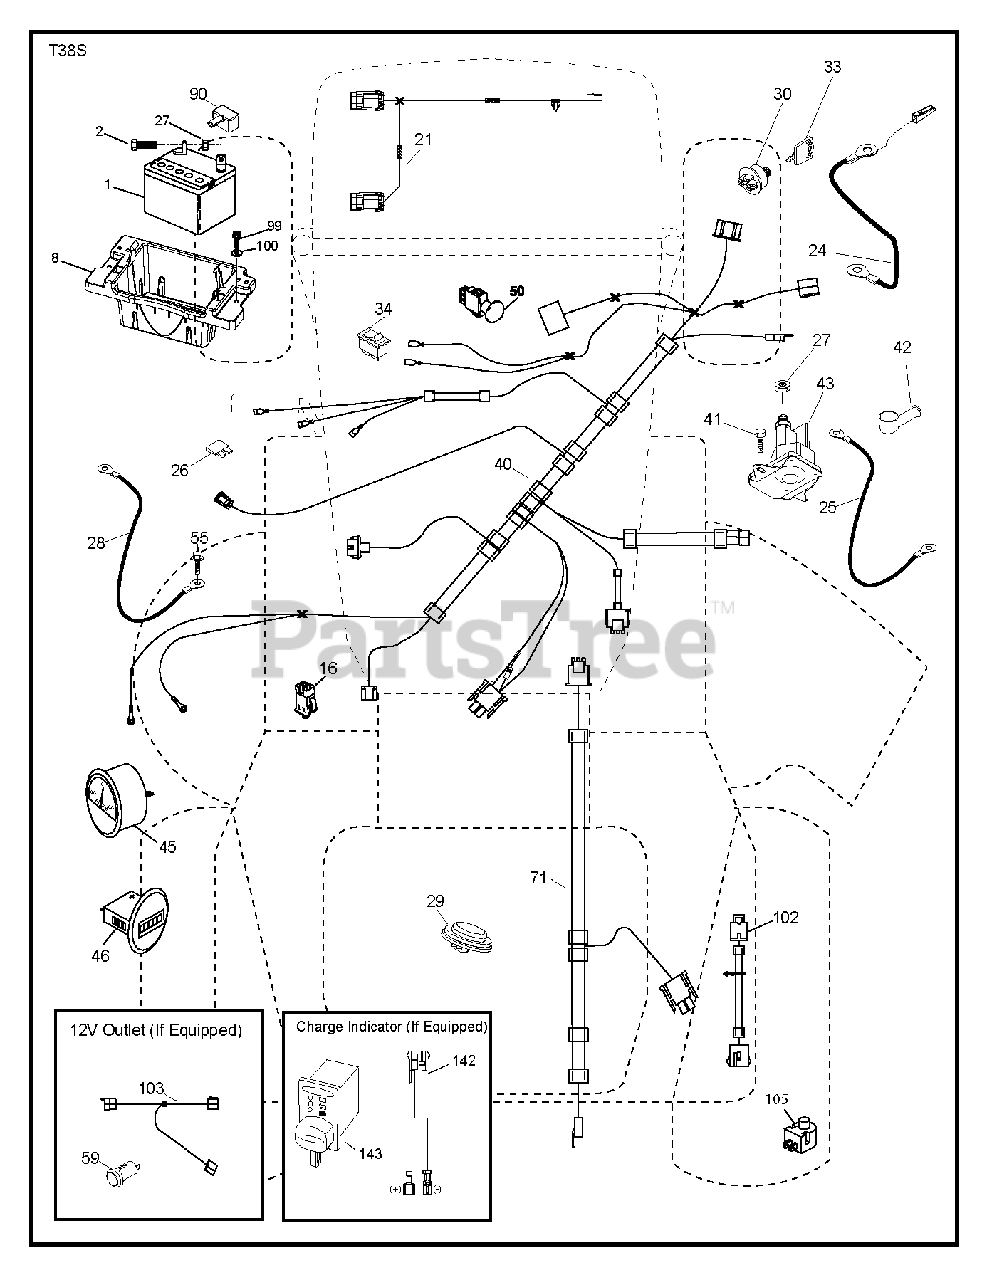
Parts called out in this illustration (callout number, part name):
1	Battery, Dry 30 Amp
2	BOLT.HEX.1/4.X.3/4.DICHROMATE
8	TRAY.BATTERY BOX.FRONT
16	SWITCH INTERLOOK PUSH-IN
21	HARNESS LIGHT ASSY TRACTOR,
24	CABLE.FRBATT.W/WIRE.8GA.8
25	CABLE.STARTER.8GA.17.5
26	FUSE 20AMP
27	NUT
28	CABLE.GROUND.21"BLK.8GA.90T
29	SWITCH.SEAT.DELTA.OPC.
30	SWITCH.IGN.DELTA.W.LGH.ROS
33	KEY.CHAIN.BLISTER.PACK.GEN.USA
40	HARNESS IGN. DASH
41	SCREW
42	TERMINAL COVER
43	SOLENOID.W/BRASS.PLUNGER
45	GAUGE.AMMETER.SILVER/WHITE
46	GAUGE.HOUR.METER.SILVER/WHITE
50	RB PTO.SWITCH.8 TERMINAL.BLACK
55	SCREW 5/16"
71	HARNESS-CHASSIS SUB
90	COVER.TERMINAL.BATTERY
99	SCREW HEXWSHR 1/4-20X3/4
102	HARNESS PIGTAIL PCH TEX ROS
105	REVERSE SWITCH
